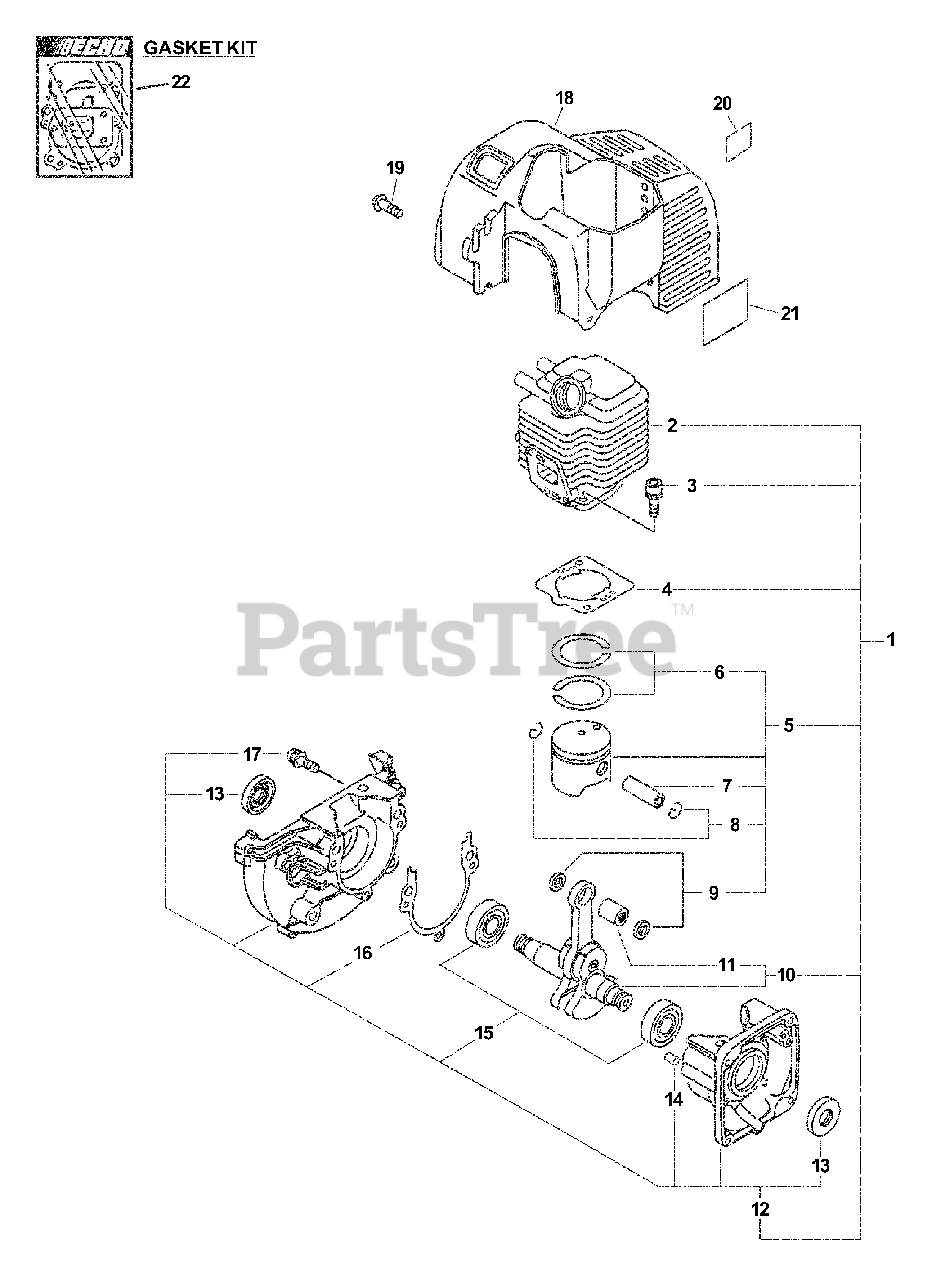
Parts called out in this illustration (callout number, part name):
1	SHORT BLOCK
2	CYLINDER
3	BOLT 5×22
4	GASKET, CYLINDER
5	PISTON KIT
6	RING, PISTON
7	PIN, PISTON 8
8	RING, SNAP
9	WASHER, THRUST
10	CRANKSHAFT ASSY
11	BEARING, NEEDLE 8
12	CRANKCASE KIT
13	SEAL, OIL 12
14	PIN, LOCATING 4
15	BEARING, BALL - 6201 C3
16	GASKET, CRANKCASE
17	BOLT 5×28
18	COVER, CYLINDER
19	SCREW 4×12
20	LABEL, CAUTION - HOT
21	LABEL, MODEL
22	GASKET KIT
